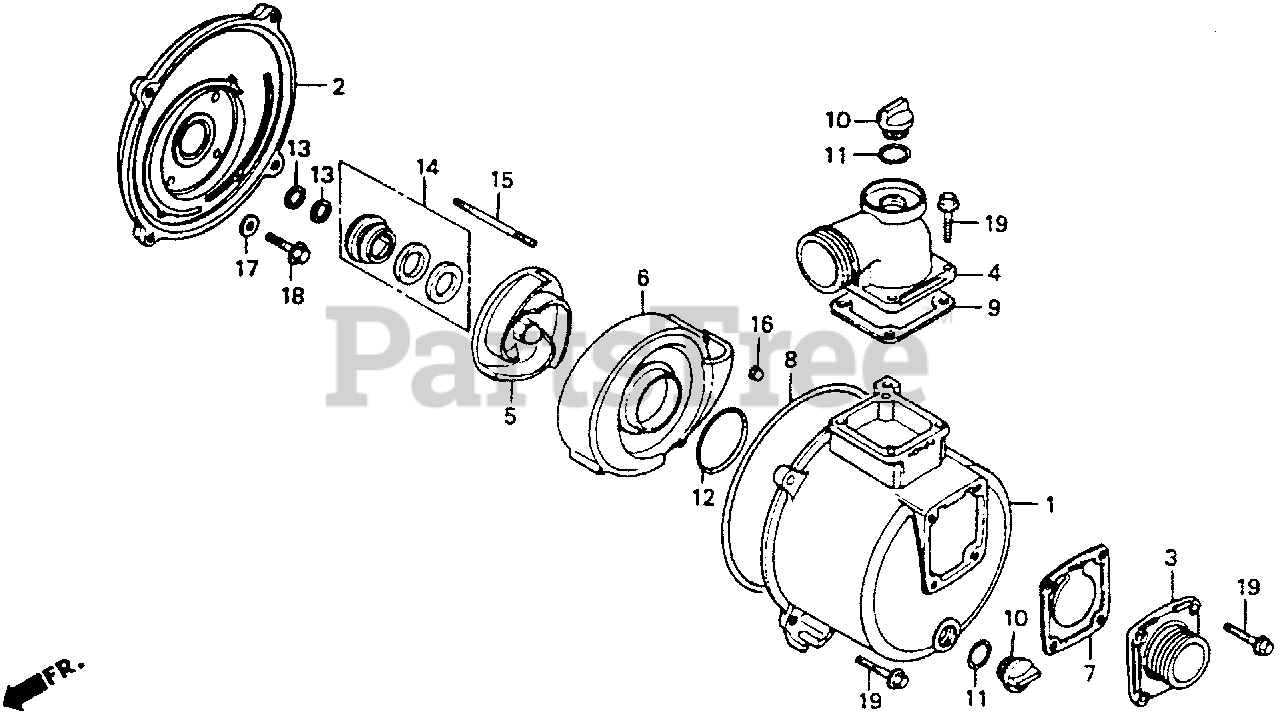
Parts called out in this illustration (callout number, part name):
1	CASING
2	COVER, CASING
2	COVER, CASING (NOT AVAILABLE)
3	PIPE, INLET (NPTF)
4	PIPE, OUTLET (NPTF)
6	CASE, VOLUTE
7	VALVE, IN.
8	RING, CASING SEAL
9	GASKET, OUTLET
10	CAP, FILLER
11	RING, SEAL (B)
12	O-RING (71X5.7)
13	SHIM, ADJUSTER
14	SEAL ASSY., MECHANICAL WATER
15	BOLT, STUD (6X50)
16	NUT, CAP (6MM)
17	WASHER, SEALING (8MM)
18	BOLT, FLANGE (8X28)
19	BOLT, FLANGE (10X32)
